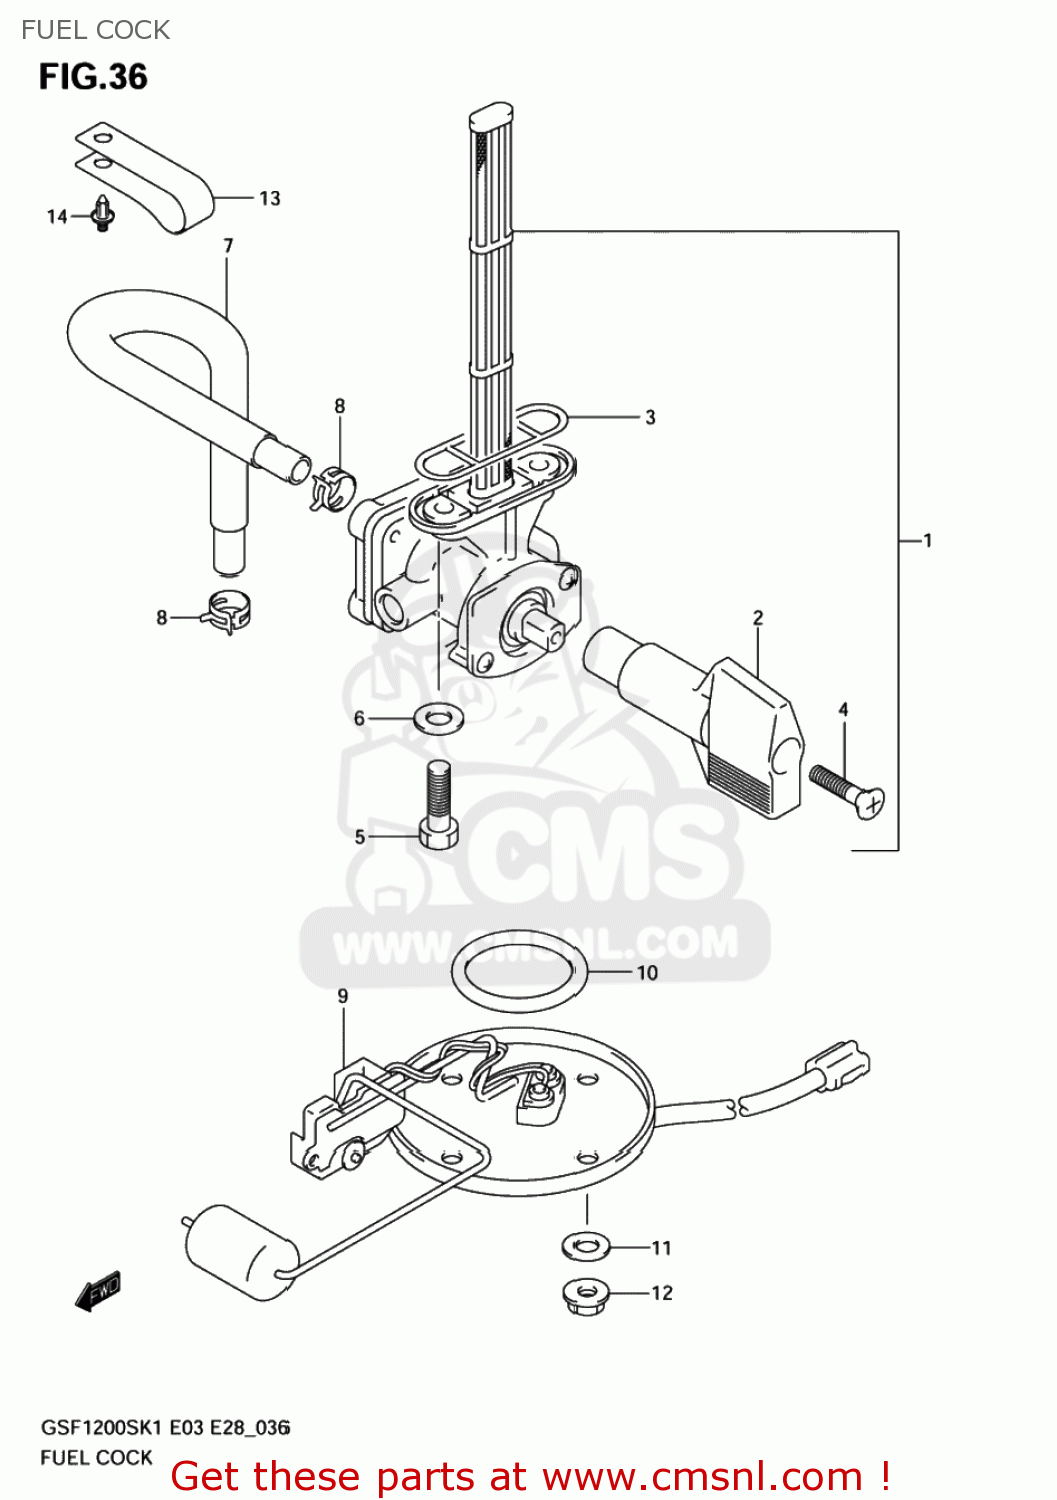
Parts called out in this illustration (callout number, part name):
1	COCK ASSY,FUEL
2	LEVER,FUEL COCK
3	GASKET,JOINT (NAS)
4	SCREW
5	BOLT(6X20)
6	GASKET(6.4X11.5X0.8) (NAS)
7	HOSE,FUEL
8	CLIP
9	GAUGE ASSY,FUEL LEVEL
10	O RING
11	WASHER(6.5X15X1.6)
12	NUT
13	CLAMP,FUEL HOSE
14	CLIP(BLACK)
